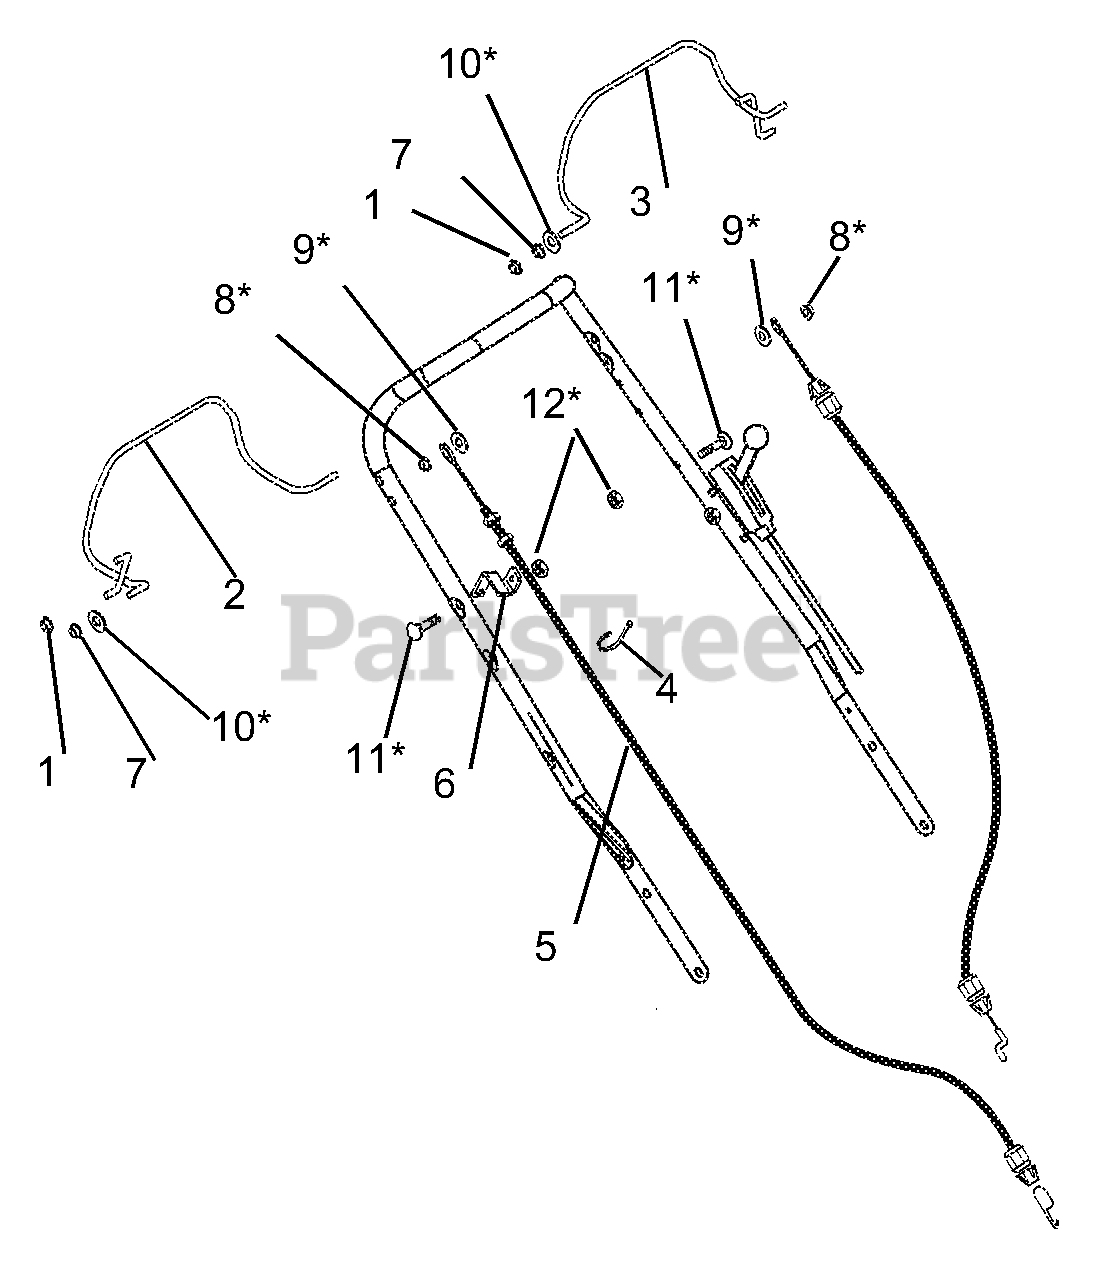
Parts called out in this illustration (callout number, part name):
1	5/16" Push Nut
2	Traction Bail
3	Engine Bail
4	Cable Tie
5	Traction Cable
6	Traction Cable Anchor
7	5/16" Bushing
8	1/4" Push Nut
9	9/32" Washer
10	1/4" Washer
11	1/2" x 1/4" Bolt
12	1/2" Locknut
